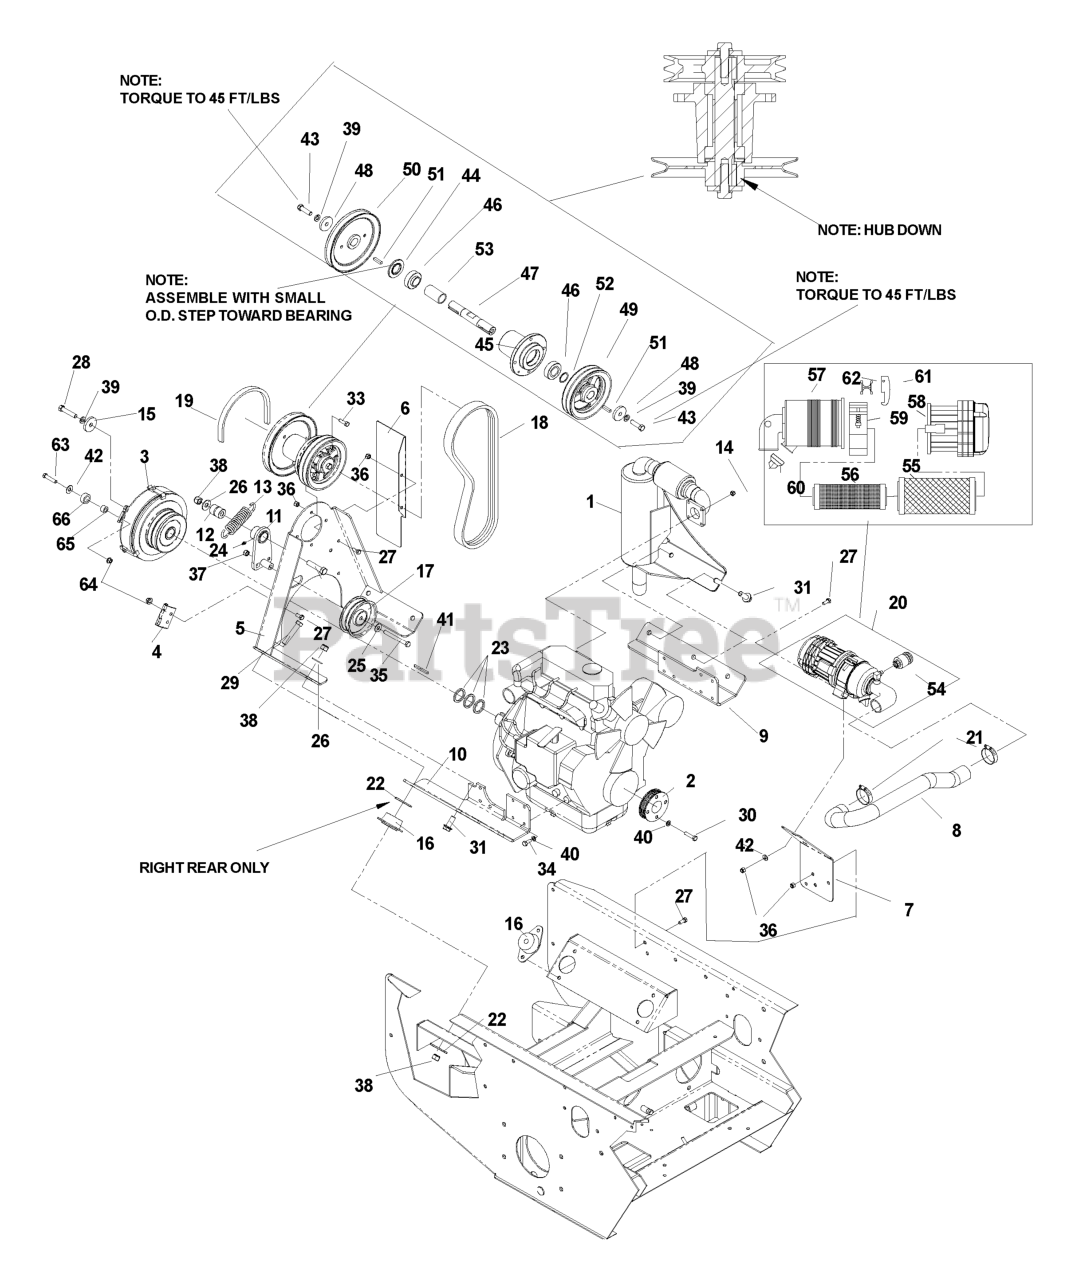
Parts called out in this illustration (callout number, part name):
1	MUFFLER NA
2	ENGINE SHEAVE
3	ELECTRIC CLUTCH
4	RESTRAINT KIT
5	JACKSHAFT MOUNT WELDMENT
6	HEAT SHIELD
7	MOUNTING BRACKET
8	AIR FILTER HOSE
9	ENGINE MOUNT-LT
10	ENGINE MOUNT-RT
11	ARM WELDMENT
14	NUT M8-1.25 STOVER
15	SPINDLE WASHER
18	BELT, PRIMARY BZ
19	ENGINE, BELT MULE
20	AIR FILTER ASSY - NON-TURBO
22	WASHER, HEAVY
23	BUSH 1-1/8 X 10 GA ZD
24	GREASE ZERK LONG
25	WASHER 3/8 SAE FLAT
26	WASHER 1/2 FLAT
27	HCS 5/16C X 3/4
28	BOLT 7/16F X 2 1/2
29	HCS 1/2C X 2 3/4
30	HTB M8-1.125 X 25MM
31	HCS 1/2C X 1 1/4 SERRATED HEAD
32	HEX SCREW 1/2-13 X 2.5" GR 5
33	HCS 5/16C X 1
35	HCS 3/8-16 X 3-1/2 GR5 ZD
36	NUT 5/16 NYLOC
37	NUT 3/8-16 NYLOC
38	NUT 1/2-13 HEX NYLOC ZD
39	WASHER 7/16 LOCK
40	WASHER.LOCK.HVY.HLCL.SPR.5/16
41	KEY 1/4 SQ X 2-1/2
42	WASHER 5/16 FLAT
43	HCS 7/16F X 1 1/2
44	COMBO SPACER
45	HOUSING, DIE CAST
46	BEARING
48	SPINDLE WASHER
51	KEY 1/4 SQ X 1 1/8
52	BUSHING.MACHINE.18.GAUGE
55	AIR FILTER
56	SAFETY ELEMENT
57	BODY - 90 DEG
58	PRECLEANER ASM
59	MOUNTING BRACKET
63	HCS 5/16C X 1 1/4
64	NUT 5/16C WHIZ
